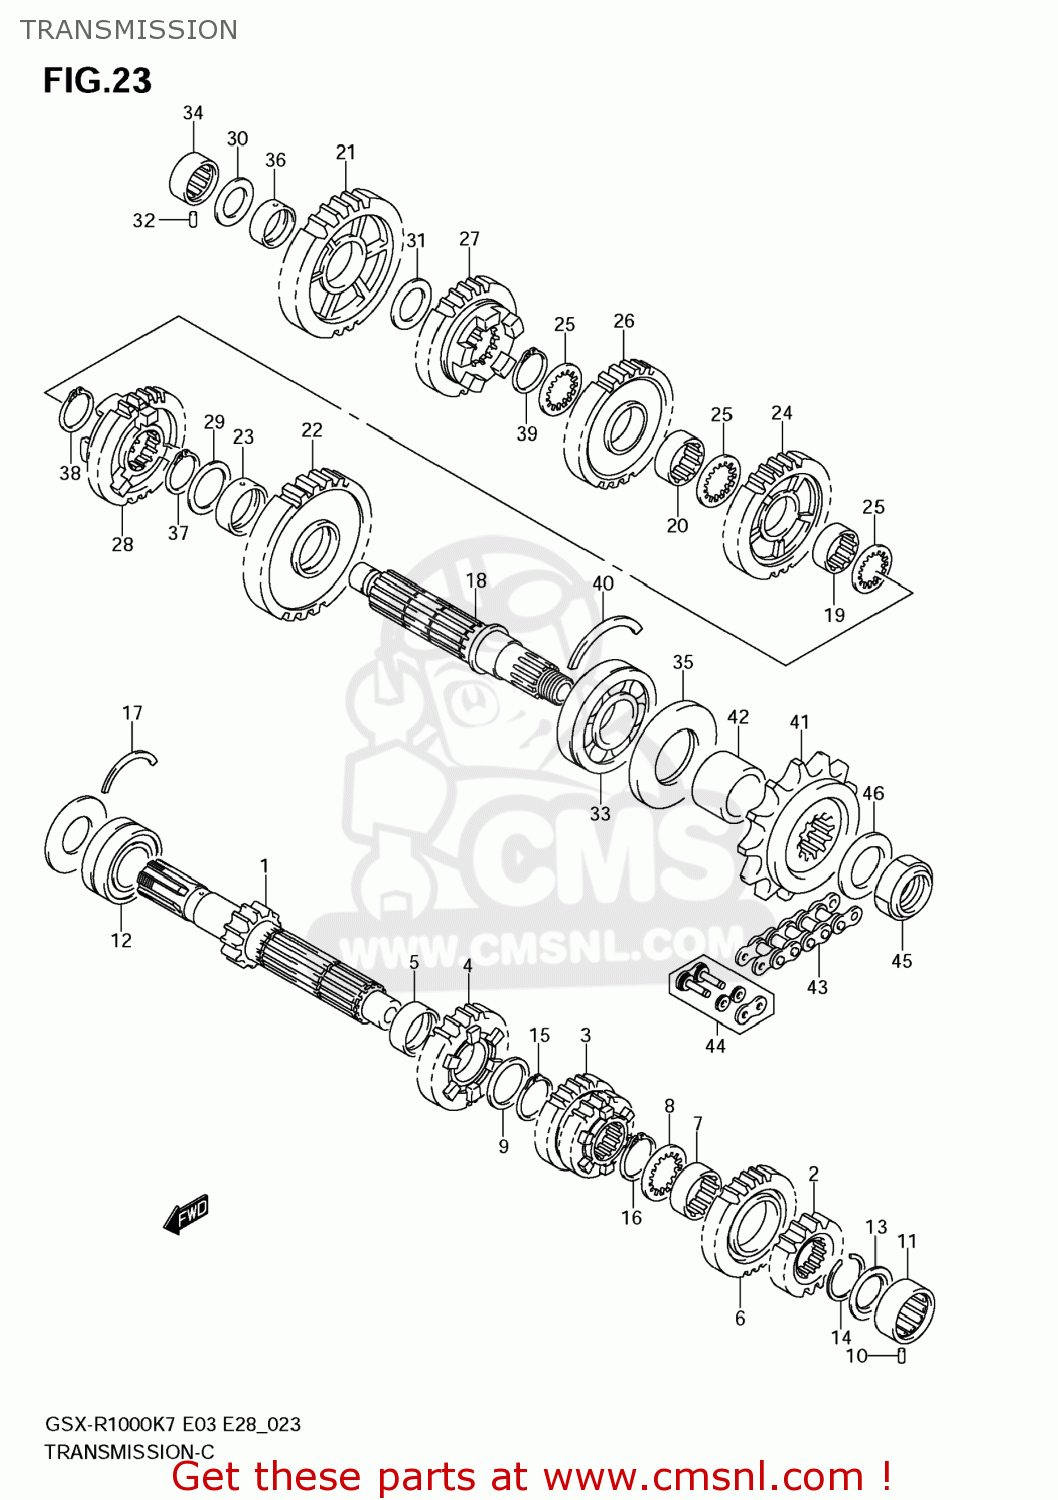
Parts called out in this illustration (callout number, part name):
1	SHAFT,COUNTER
2	GEAR,2ND DRIVE
3	GEAR,3RD & 4TH DRIVE
4	GEAR,5TH DRIVE
5	BUSH,5TH DRIVE GEAR
6	GEAR,6TH DRIVE
7	BUSH,6TH DRIVE GEAR
8	WASHER,LOCK
9	SHIM(27X36X2.5)
10	PIN(6X10)
11	BEARING(20X34X13.5)
12	BEARING(25X52X20.6)
13	SEAL,OIL(20X31.2X2.7)
14	CIRCLIP
15	CIRCLIP
16	CIRCLIP
17	C RING
18	SHAFT,DRIVE
19	BUSH
20	BUSH
21	GEAR,1ST DRIVEN
22	GEAR,2ND DRIVEN
23	BUSH,2ND DRIVEN GEAR
24	GEAR,3RD DRIVEN
25	WASHER,3RD & 4TH DRIVEN
26	GEAR,4TH DRIVEN
27	GEAR,5TH DRIVEN
28	GEAR,6TH DRIVEN
29	WASHER(27X36X1)
30	SHIM(20X34X1)
31	SHIM(22X34X1)
32	PIN(6X10)
33	BEARING(28X70X18)
34	BEARING(20X34X13.5)
35	SEAL,OIL(34.8X70X6)
36	BUSH
37	CIRCLIP
38	CIRCLIP
39	CIRCLIP
40	C RING
41	SPROCKET,ENGINE(NT:17)
42	SPACER,ENG SPROCKET
43	CHAIN,DRIVE
44	JOINT SET,DRIVE CHAIN
45	NUT
46	WASHER(25X40X1.4)
